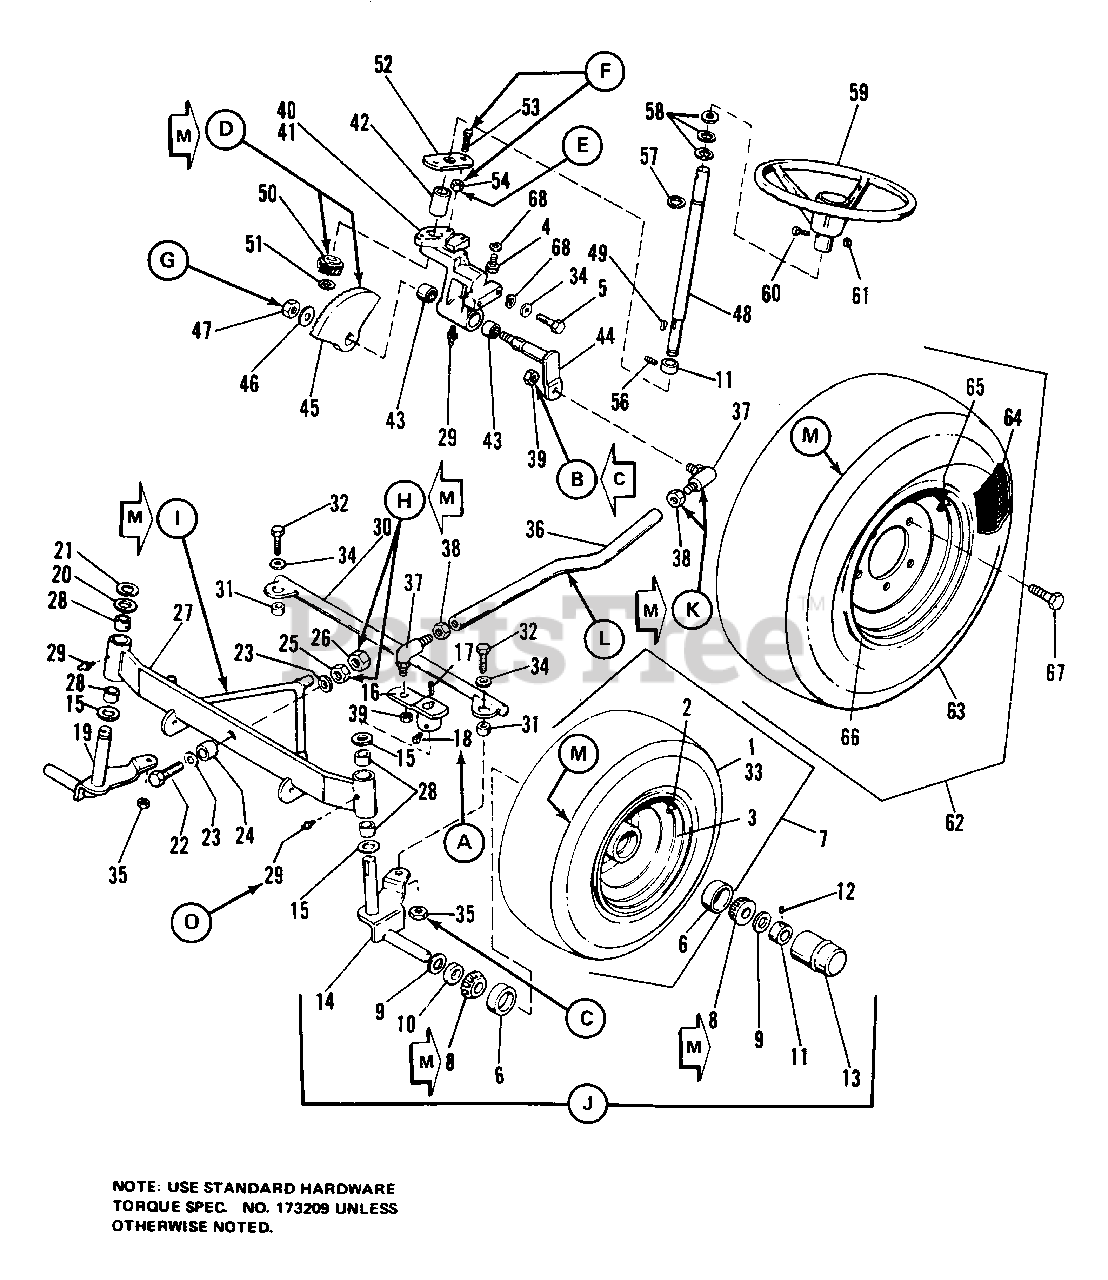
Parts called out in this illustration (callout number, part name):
2	VALVE STEM & CAP
3	WHEEL ASSY
4	CAPSCREW, Hex, 3/8-16 x 3/4
5	CAPSCREW, Hex, 3/8-16 x 7/8
6	CUP, Bearing
7	WHEEL & TIRE ASSY
8	CONE, Bearing
11	COLLAR, Set
12	SETSCREW, Sq. Hd., Cup Pt., 5/16-18 x 5/16
13	CAP, Hub
14	SPINDLE ASSY, LH.
16	ARM, Steering, L.H.
17	KEY, Square
18	SETSCREW, 5/16-18 x 1/2
19	SPINDLE ASSY, R.H.
21	"E" RING, External
22	CAPSCREW, Hex Hd., 1/2-13 x 2-1/4
23	WASHER, Plain, 1/2
25	LOCKNUT, Hex, 1/2-13
26	NUT, Jam Hex, 1/2-13
27	FRONT AXLE ASSY
29	FITTING, Grease
30	TIE ROD ASSY
32	CAPSCREW, Hex Hd., 3/8-16 x 1-1/4
33	TIRE, 16 x 6.50-8, Goodyear
33	TIRE, 16 x 6.50-8, Carlisle
34	WASHER, Plain, 3/8
35	LOCKNUT, Hex, 3/8-16
36	LINK, Drag
37	JOINT, Ball
38	NUT, Jam Hex, 1/2-20
39	LOCKNUT, Hex, 1/2-20
40	STEERING HOUSING ASSEMBLY
41	HOUSING, Steering
43	BEARING, Needle
44	STEERING ARM ASSEMBLY, (Includes Ref. Nos. 41, 42, 43)
45	GEAR, Bevel
46	WASHER, Plain, 7/16
47	LOCKNUT, Hex, 7/16-14
48	SHAFT, Steering
49	KEY, Woodruff, No. 6, 5/32 x 5/8
50	PINION, Bevel
51	"E" RING
52	PLATE, Steering
53	CAPSCREW, Hex Hd., 3/8-16 x 1-1/4
54	LOCKNUT, 3/8-16
56	SETSCREW, Sq. Hd., 5/16-18 x 1/4
57	RING, Retaining
59	WHEEL, Steering
60	CAPSCREW, Hex Hd., 5/16-18 x 1-1/4
61	LOCKNUT, Flange, 5/16-18
62	WHEEL & TIRE ASSEMBLY (7012 Only)
62	WHEEL & TIRE ASSY, Turf (1690427 & 1690431 Only)
62	WHEEL & TIRE ASSY, R.H. Ag. (1690429 & 1690433 Only)
62	WHEEL & TIRE ASSY, L.H. Ag. (1690429 & 1690433 Only)
63	TIRE, 23-8.50 x 12, Goodyear Turf (7012 Only)
63	TIRE, 23-8.50 x 12, Carlisle Turf (7012 Only)
63	TIRE, 23 x 10.50-12, Carlisle Turf (1690427 & 1690431 Only)
63	TIRE, 23 x 10.50-12, Firestone Turf (1690427 & 1690431 Only)
63	TIRE, 23 x 10.50-12, Goodyear Ag. (1690429 & 1690433 Only)
64	TUBE (7012 0nly)
64	TUBE (7016 Only)
65	STEM & VALVE CAP (7012 0nly)
66	WHEEL, Drive (7012 Only)
68	LOCKWASHER, 3/8
